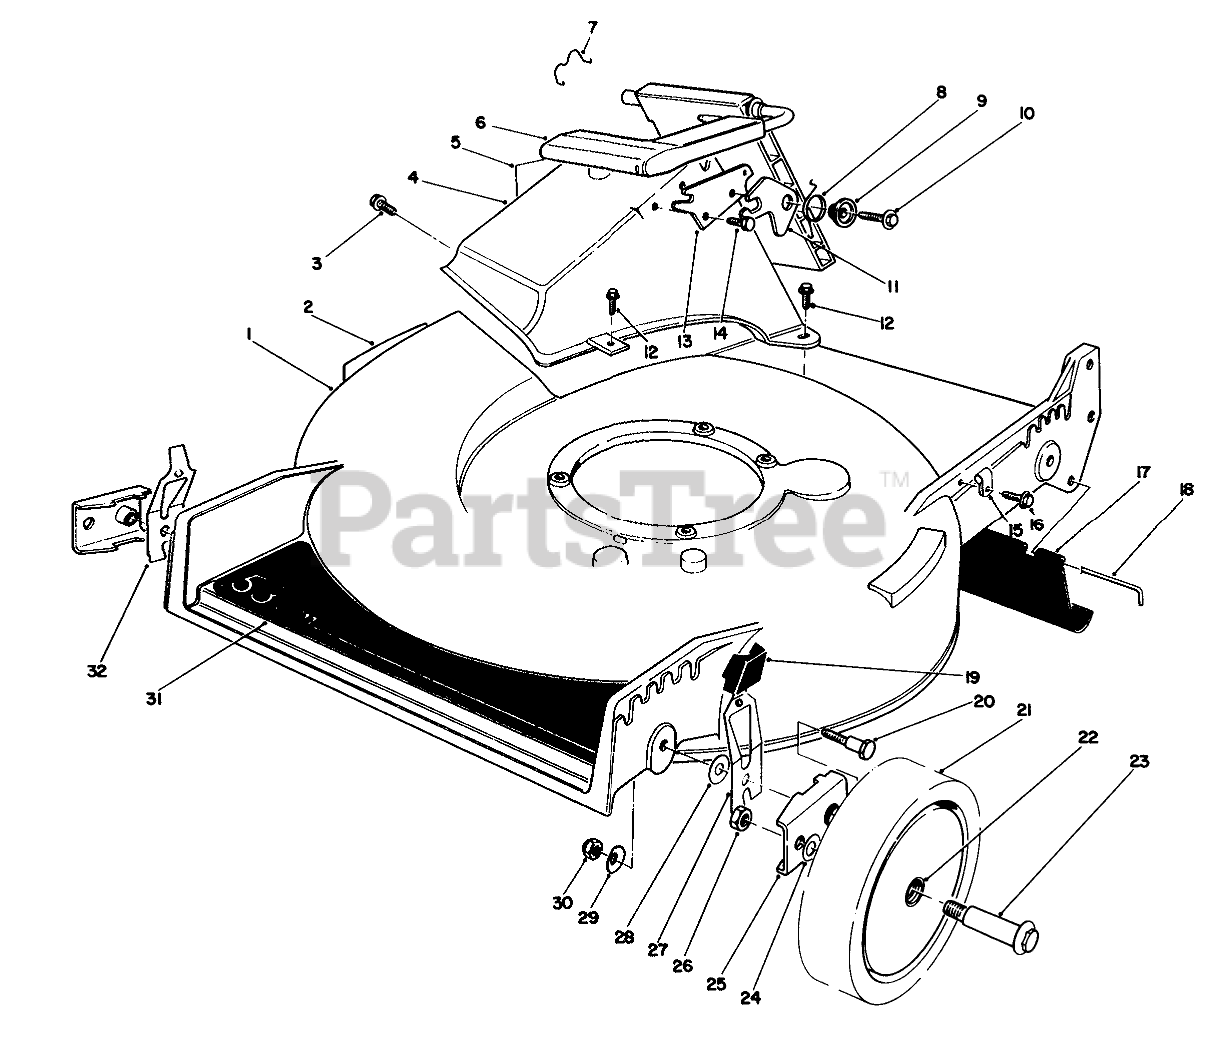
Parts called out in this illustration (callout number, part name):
1	Housing (Incl. Ref. #2)
1	Engine
2	DECAL-DANGER
2	TORO LOGO PLT
3	SCREW AND WASHER ASM
3	SPRING-COMPRESSION
4	Tunnel-Discharge (Incl. Ref. #5)
4	Screw-Shoulder
5	DECAL - DANGER
5	BRAKE PLATE ASM
6	Discharge Door Assembly
6	THO FORM SCREW M6 X 1
7	Retainer-Door
7	RIVET-PLASTIC
8	TORSION SPRING
8	STRAP-GROUND
9	DOOR SPACER
9	Strap-Insulation
10	SCREW-HWH
10	Plate-Mounting
11	SAFETY LATCH
11	CABLE CLAMP
12	SCREW-HWH
12	STOP-GROUND STRAP
13	DOOR LATCH PLATE
13	SCREW
14	SCREW-PLASTITE
14	DECAL-HV INT'L
15	CLAMP-CABLE
15	Staple
16	SCREW
17	SHIELD-TRAILING
17	THRD FORMING SCREW
18	ROD-SHIELD
18	TUBULAR SPACER
19	KNOB-ARM
19	GAS CAP ASM
20	PIVOT SCREW
20	TANK ASM
21	Wheel & Tire Assembly (Inc. Ref. #22)
21	CLAMP-FUEL LINE
22	BUSHING
22	LINE-GAS
23	BOLT-WHEEL
23	FILTER-FUEL
24	WASHER
24	HOSE-FUEL
25	HP PIVOT ARM ASM
25	SCREW-HWHTF
26	Nut
26	BLADE RETAINER
27	L. HP SPRING ARM ASM
27	BLADE-21in
28	WASHER-PIVOT
28	WASHER-LOCK
29	WASHER-BELLEVILLE
29	SCREW-BLADE
30	NUT-LOCK, NI
31	Decal-53cm
32	R HP SPRING ARM ASM
